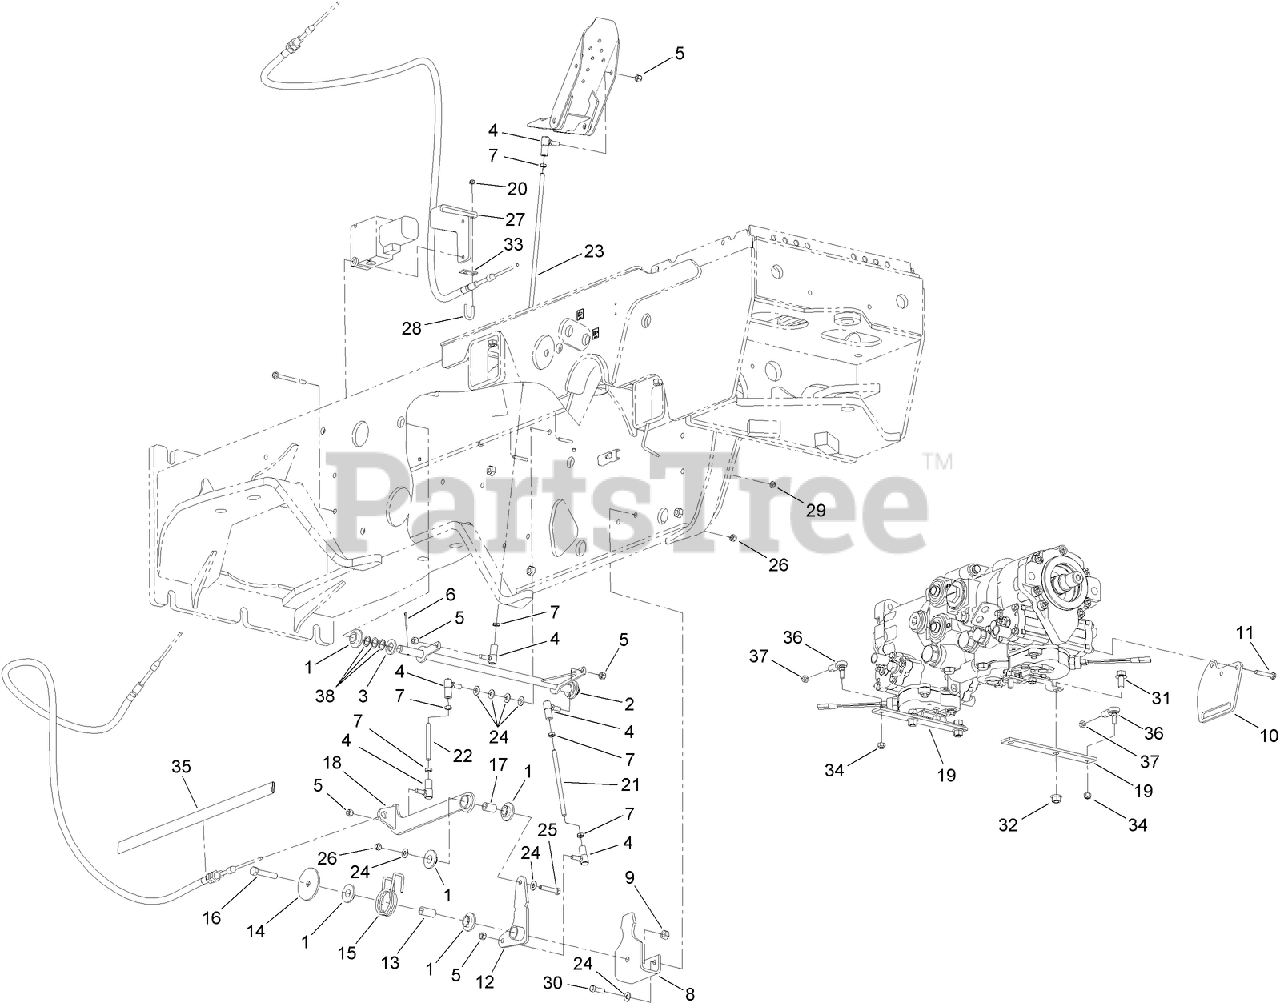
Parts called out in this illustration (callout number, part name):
1	BUSHING-INSERT, PLASTIC
2	SHAFT-CONTROL
3	WASHER-FLAT
4	JOINT-BALL
5	NUT-HEX
6	PIN-COTTER
7	NUT-HJ
8	CHANNEL-MOUNTING, BELLCRANK
9	LOCKNUT
10	STOP-LEVER, PUMP
11	SCREW-HH
12	PIVOT-BELLCRANK
14	WASHER-Special
16	SCREW-HH
17	SPACER-PIVOT, BELLCRANK
18	LINK-MOUNTING, CABLE
19	LEVER-CONTROL, PUMP
20	NUT-HF
21	ROD-Linkage
22	ROD-Linkage
23	ROD-Control
24	WASHER-FLAT
25	SCREW-HH
26	NUT-HEX
27	PLATE-MOUNT
29	NUT-HEX
30	SCREW-HH
31	SCREW-HHF
32	NUT-HF
34	NUT-LOCK
35	SLEEVE-PROTECTIVE
36	ROD END-FEMALE
37	NUT-JAM
38	WASHER-THRUST
